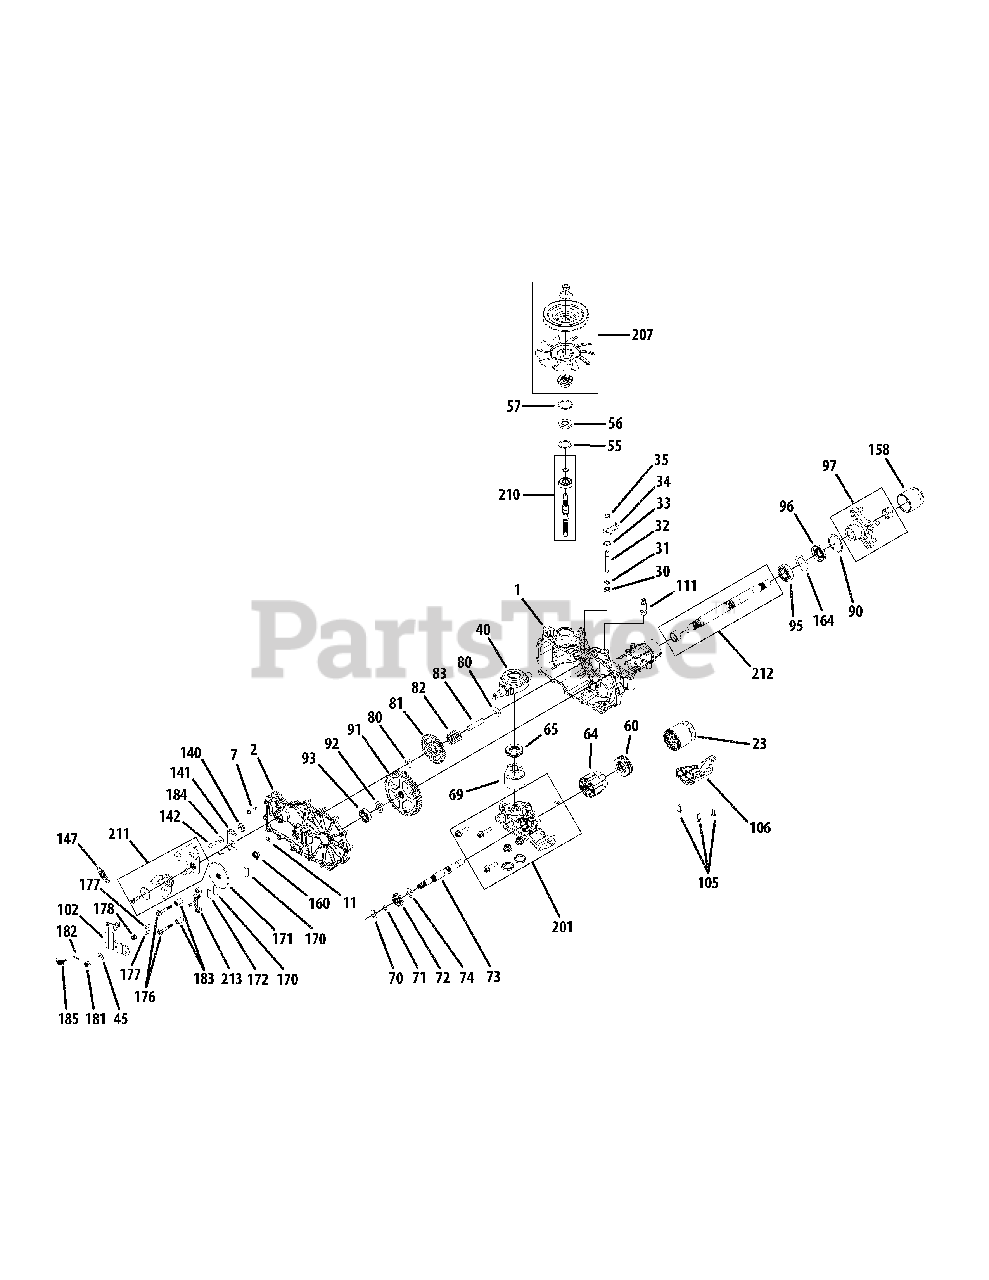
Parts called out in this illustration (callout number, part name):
1	Kit, Housing, Main, RH
2	Kit, Cover Side RH Control
7	Screw, Hex Washer
23	Filter, Spin-On 2.6 x 3.0
30	Seal, Lip, .375 x .75 x .25
31	Ring, Retaining .375 External
32	Rod, Bypass
33	Ring Retaining .750 Internal
34	Arm, Bypass
35	Ring, Ret .375 External
40	Trunnion, Swashplate
45	Washer, .34 x .88 x .06
55	Washer, 1.23 x 1.57 x .04
56	Seal, Lip 17 x 40 x 7
57	Ring Retaining Internal
60	Bearing, Thrust 35 x 62 x 18
64	Kit, 16cc Cylinder Block Assembly
65	Thrust Bearing, 30 x 52 x 13
69	Kit, Block, 7 Piston
70	Washer, .63 x 1.00 x .05
71	Ring, Reatining, Motor Shaft
72	Gear, 16T
73	Shaft, Motor
74	Washer, .71 x 1.16 x .04
81	Gear, 43T
82	Gear, 11T
83	Pin, Jackshaft
90	Ring, Retaining 2.25 Internal
91	Gear, 54T
92	Spacer, .750 x 1.00 x .257
93	Bearing, Ball 3/4 x 40mm x 12mm
95	Bearing, Ball 25.4 x 52 x 15
96	Seal, Lip, 1.0 x 2.06 x .38
97	Kit, Hub 4-Bolt
102	Arm, Brake
105	Screw, Hex Washer 1/4-20 x .75
106	Guard, Filter, RH
111	Kit, Fitting 1/2 Beaded 9/16 SAE
140	Spacer, .320 x 1.005 x .150
141	Arm, Return Left
142	Socket Cap Screw, 5/16-24 x 7/8
147	Spring, Extension
158	Cap, Axle
160	Seal, Lip .625 x 1.00 x .250
164	Spacer, 1.355 x 2.035 x .021
170	Puck, Brake
171	Rotor, Brake
172	Puck, Plate
176	Screw, .250-20 x 2.0 HFS Patch
177	Pin, Brake Actuating
178	Compression Spring
181	Nut, Castle 5/16-24
182	Pin, Cotter 3/32 x 3/4
184	Washer, .34 x .88 x .06
185	Spring, Brake Arm Bias
201	Kit, Center Section RH
207	Kit, Fan Pulley
207	Fan Only
207	Pulley Hub
210	Kit, Input Shaft
211	Kit, RTN Bidirectional
212	Kit, Shaft Axle
213	Kit, Brake Yoke
